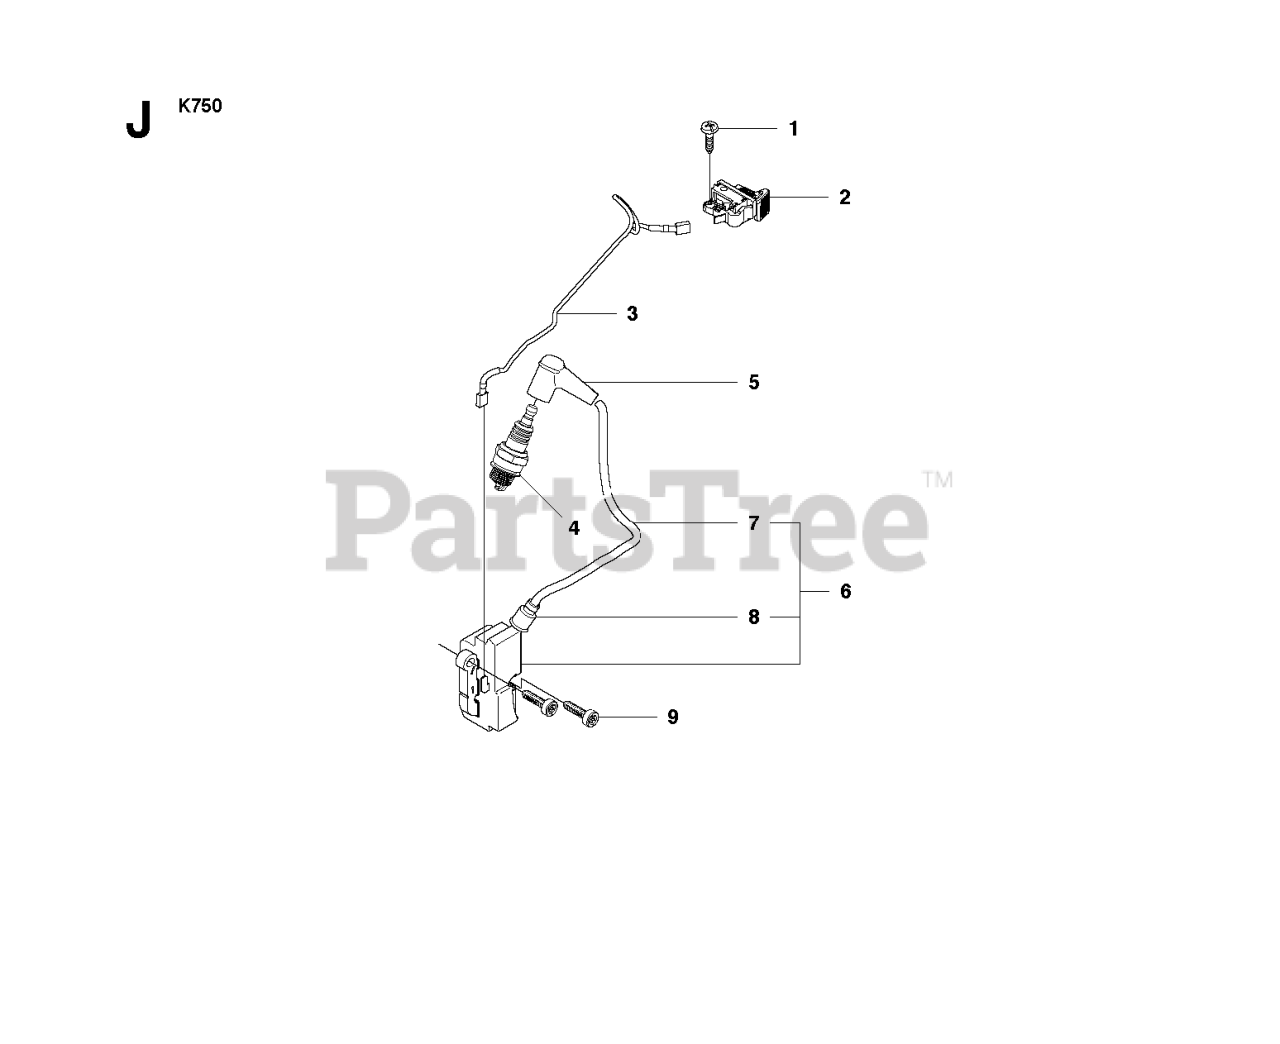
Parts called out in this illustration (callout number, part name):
2	STOP SWITCH
3	CABLE STOP SWITCH
4	SPARK PLUG RCJ6Y NLA
5	SPARK PLUG CONN. KIT
6	IGNITION MODULE
7	CABLE STOP SWITCH
8	INSULATING CAP
